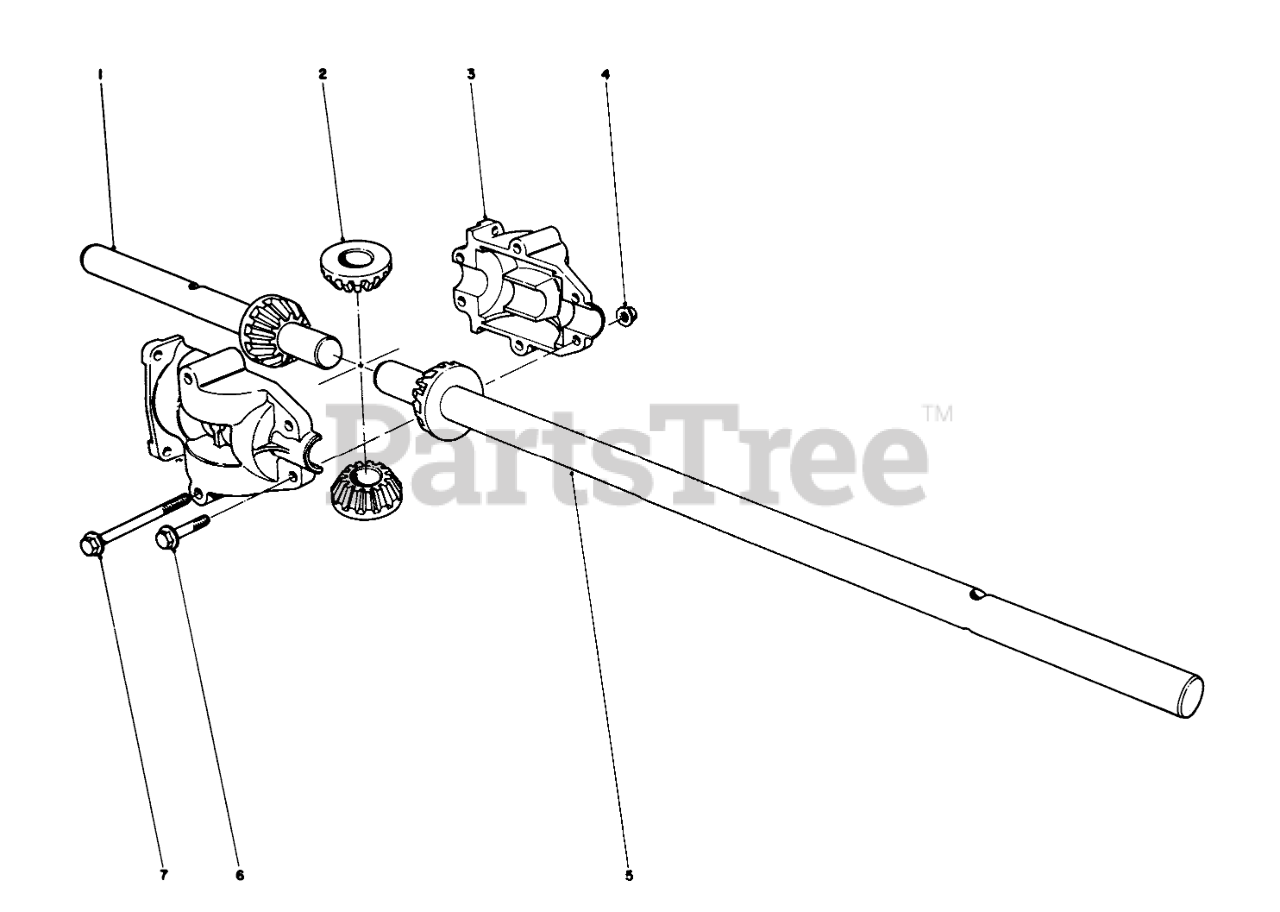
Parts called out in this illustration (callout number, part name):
1	Short Shaft
3	Housing Half
4	NUT-HHF
5	Long Shaft
